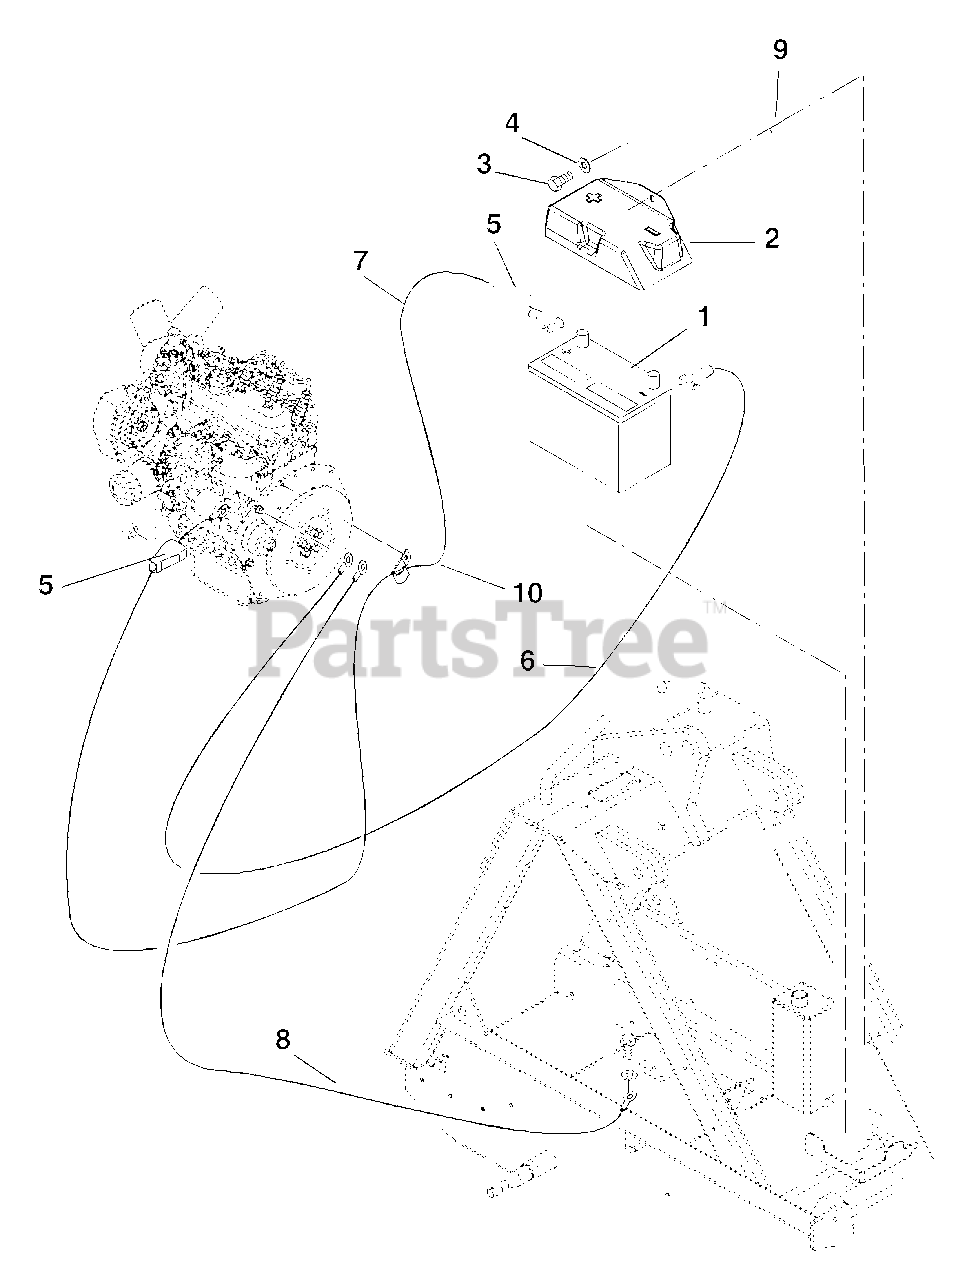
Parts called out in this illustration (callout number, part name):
2	Cover-Battery
3	Bolt-Hex M8 x 1.25 x 16
4	Washer-Flat-Steel .344 x .688 x .065
5	Cover,Battery Terminal
6	Cable-Battery Positive
7	Cable-Battery Negative
8	Wire-Ground
9	Bracket, Battery Holddown
10	J-Clamp
